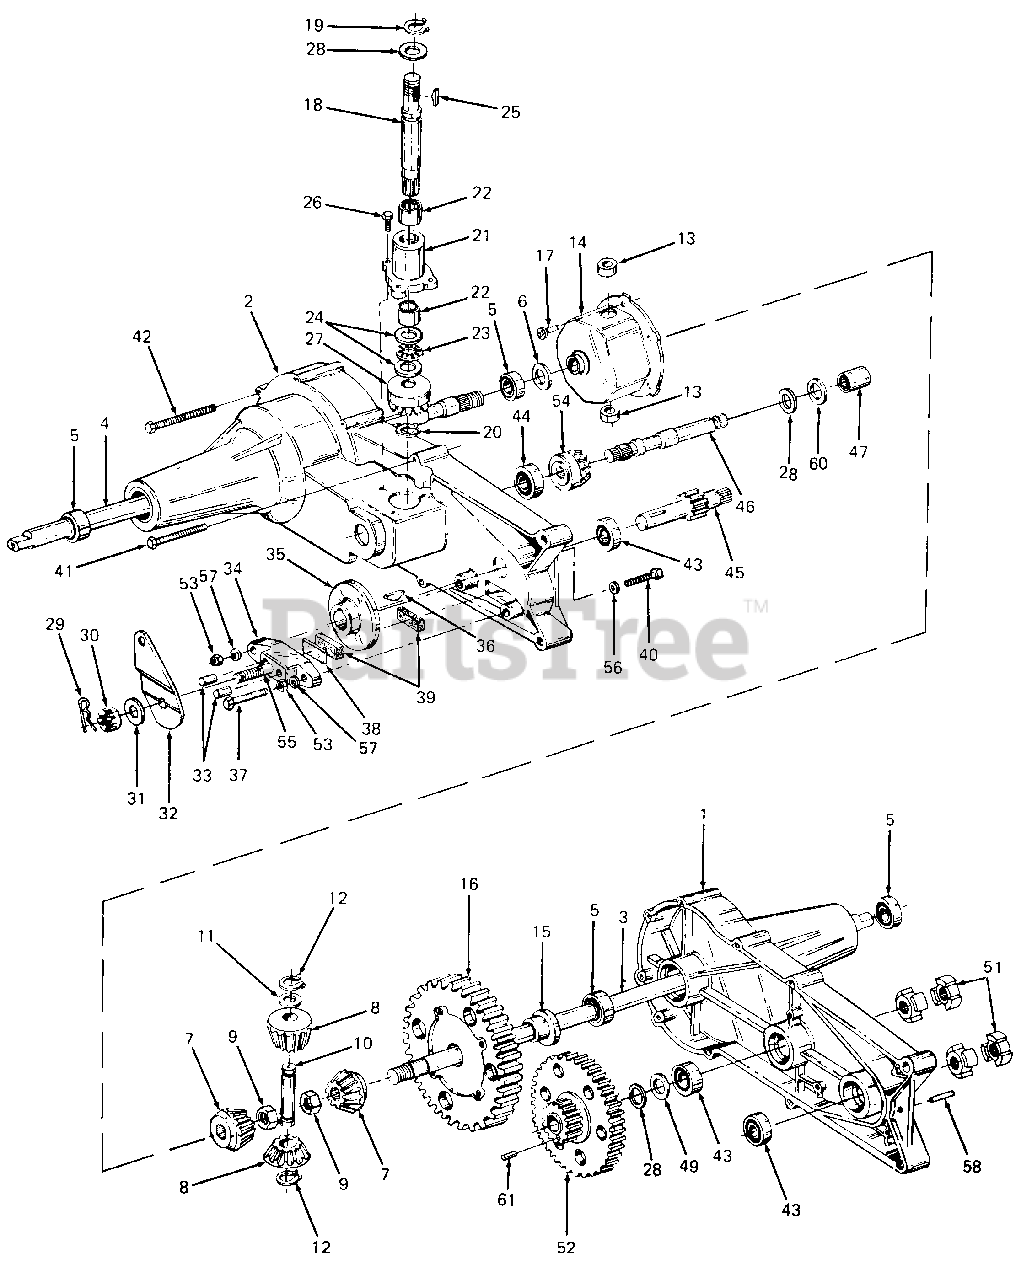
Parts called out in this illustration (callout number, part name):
1	Housing Half L.H.
2	Housing Half R.H.
5	Bearing, Ball 4
6	Washer, Flat, .76 x 1-1/8" x .306 Thk. Hdn.
7	Gear, Miter 2
8	Gear, Miter 2
9	Nut, Hex Jam Patch Lock, 1/2-20 0 2
10	Shaft, Cross
11	Washer, Flat .505 I.D. x 1.0
12	Ring, Snap 2
13	Bearing, Thrust 2
14	Housing Ass'y. Differential
15	Bearing, Flange, .75 I.D. x .587
16	Gear, Differential, 72 Tooth
17	Screw, Pan Hd. Patch Lock 1/4-20 x .50 Lg. 4
18	Shaft, Input
19	Ring, Snap
20	Ring, Retaining, Ext. 7/16 Dia.
21	Bearing, Input Housing
22	Bearing, Needle, 5/8 I.D. x .50 Lg. 2
23	Bearing, Thrust
24	Washer, Flat, 5/8 I.D. x 1.12 O.D. x .030 Thk. 2
25	Key #4 Hi-Pro, 3/32 x 5/8 Dia. (Hdn.)
26	Screw, Hex Patch Lock, 1/4-20 0 x 3/4 Lg. 3
27	Gear, Input Pinion, 17 Tooth
28	Washer, Flat, .62 I.D. x 1.0 O.D. x .030 Thk. 2
29	Pin, Cotter 1
30	Nut, Castle, 5/16-24 1
31	Washer, Flat, .343 x .88 x .062 0 Thk. 1
32	Arm, Brake Actuator 1
33	Pin, Actuating, 5/16 Dia. 2
34	Yoke, Brake 1
35	Disc, Brake 1
36	Key, Hi-Pro, 3/16 x 5/8 Dia. 1
37	Screw, Hex Patch Lock, 1/4-20 x 1.5 Lg. 1
38	Plate, Puck 1
39	Puck, Brake 2
40	Screw, Hex Cap, 1/4-20 x 1.5 Lg. 1
41	Screw, Hex Self-Tap, 1/4-20 x 2.0 Lg. 2
42	Screw, Hex Self-Tap, 1/4-20 x 2.75 Lg. 6
43	Bearing, Ball 3
44	Bearing, Ball 1
45	Shaft, Pinion w/11 Tooth Gear 1
46	Shaft, Drive 1
47	Bearing, Needle 1
49	Washer, Flat, 5/8 x 1.12 x .060 0 Thk. 1
51	Coupling 4
52	Gear, Tooth 60 & 17 1
53	Nut, Hex Jam, 1/4-20 1
54	Gear, Drive Pinion 17 Tooth 1
55	Bolt, Square Hd. 5i16-24 1
56	Washer, Flat, .265 x .938 x .12 0 Thk. 1
57	Washer, Lock, 1/4 1
58	Pin, Roll, 3/16 Dia. x .50 Lg. 1
60	Bronze Thrust Brg. 5/8" I.D. 1
61	Dowel Pin 3/32" x 1/4" 1
